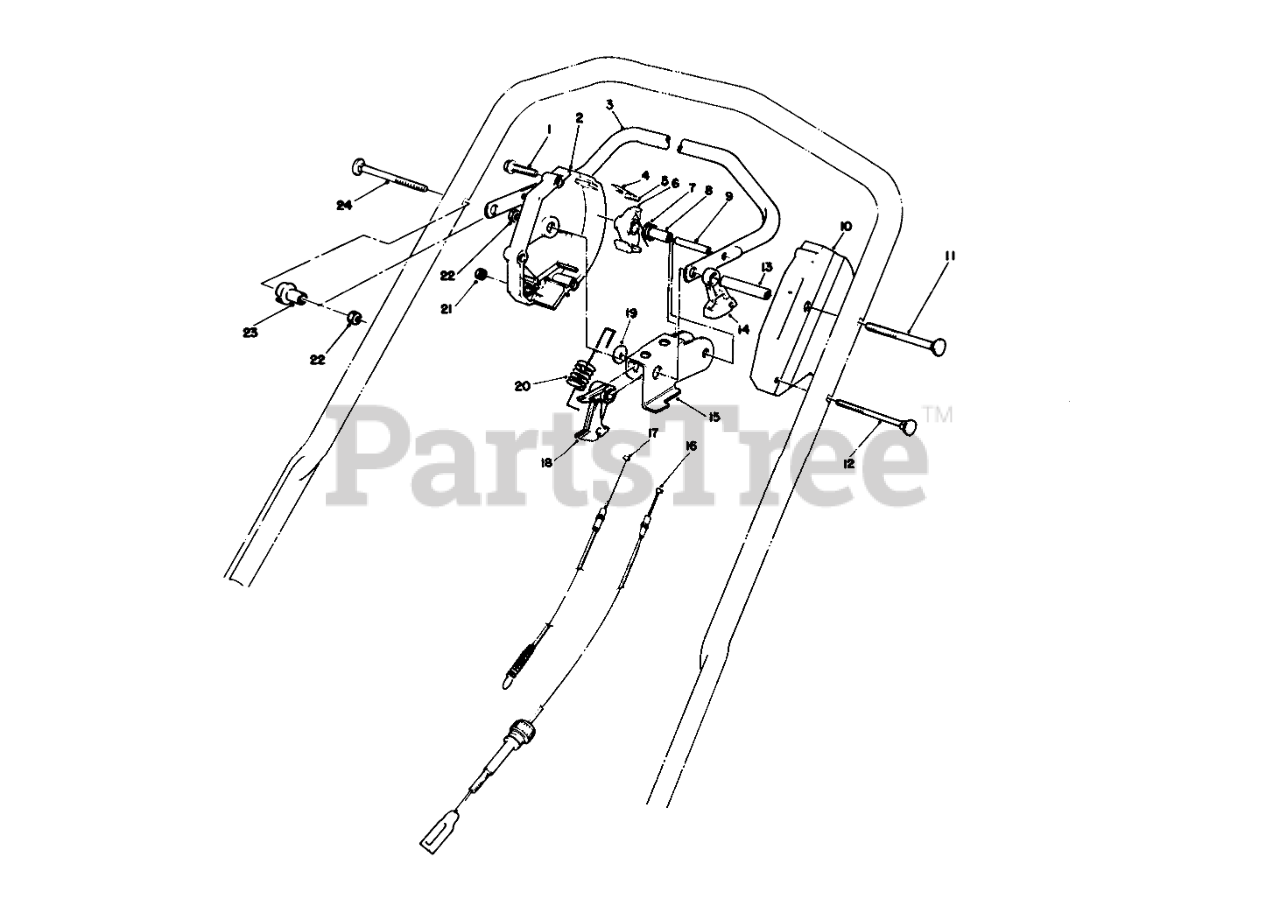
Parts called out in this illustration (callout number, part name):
1	SCREW-HWHTF
2	Housing-Control R.H. (Incl. Ref. #4 & 5)
3	Bar-Control
4	SPRING-LEAF
5	PIN-INSERT
6	HOOK-CONTROL
7	SPRING-TORSION
8	SPACER
9	PIN-ROLL, SLOTTED
10	HOUSING-CONTROL, LH
11	5/16-18 X 3 HNDLE SCREW
12	HANDLE SCREW
13	TUBING-SPACER
14	LEVER-TRACTION
15	ROCKER
16	TRACTION CABLE
17	Cable-Clutch
18	LEVER-CABLE
19	PLASTIC WASHER
20	DETENT SPRING
21	NUT-HEX
22	NUT-LOCK, NI
23	SPACER-SUPPORT
24	5/16-18 X 2 HNDLE SCREW
